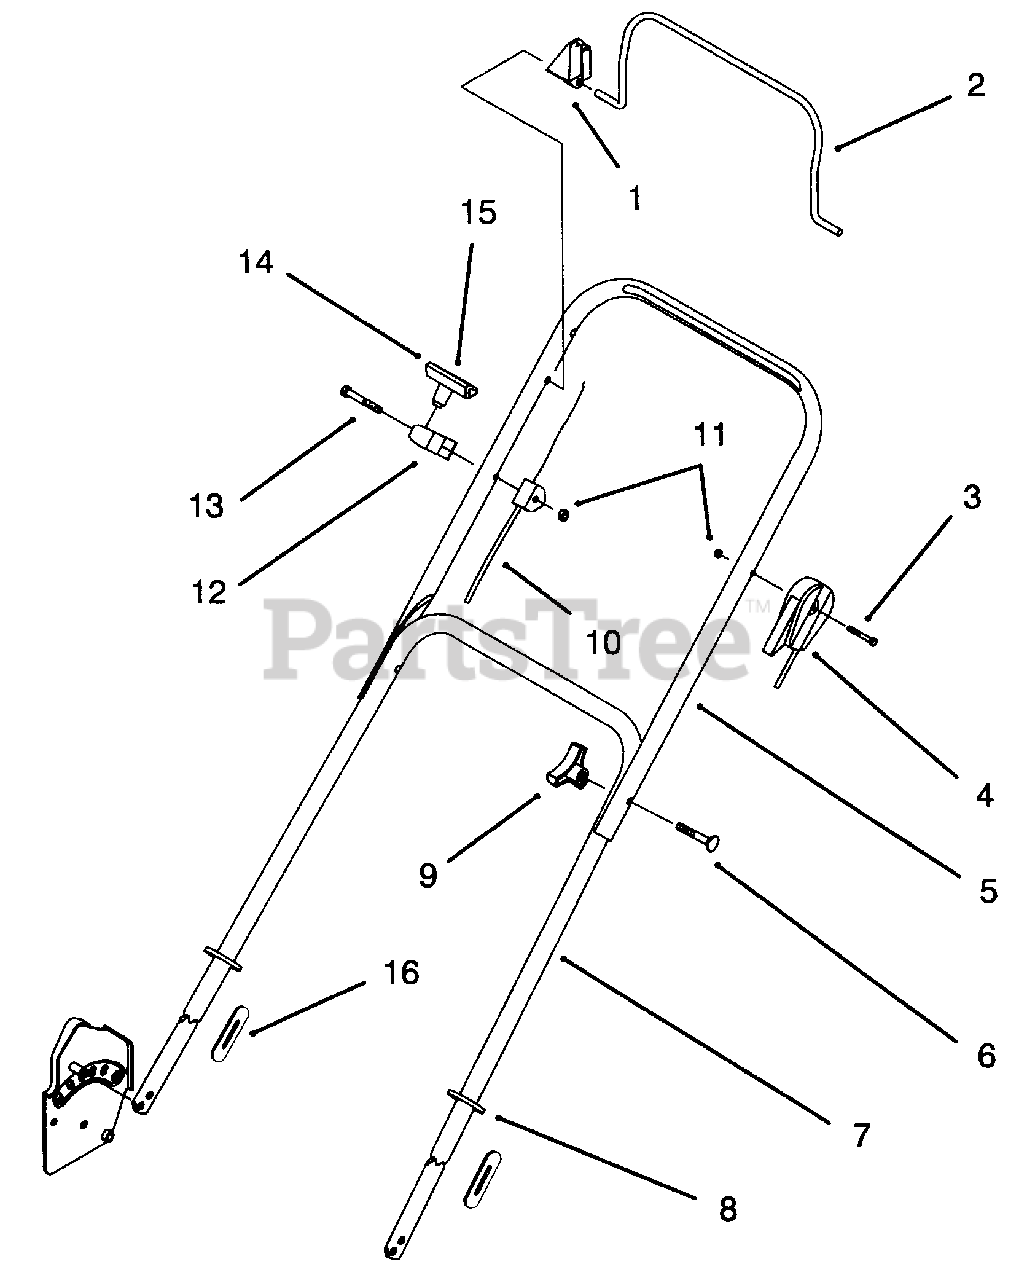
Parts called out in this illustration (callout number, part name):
1	Stop-Pivot
2	Bail-Flywheel Brake
3	Screw-Hex Hd. Cap
4	Cable-Throttle
5	Handle-Upper
6	Screw-Handle
7	Handle-Lower
8	Tie-Cable
9	Knob
10	Cable-Flywheel Brake
11	Nut-Lock
12	Guide-Rope
13	Screw-Hex Hd Cap
14	Handle-Starter
15	Clip-Rope Insert
16	Guard-Handle
